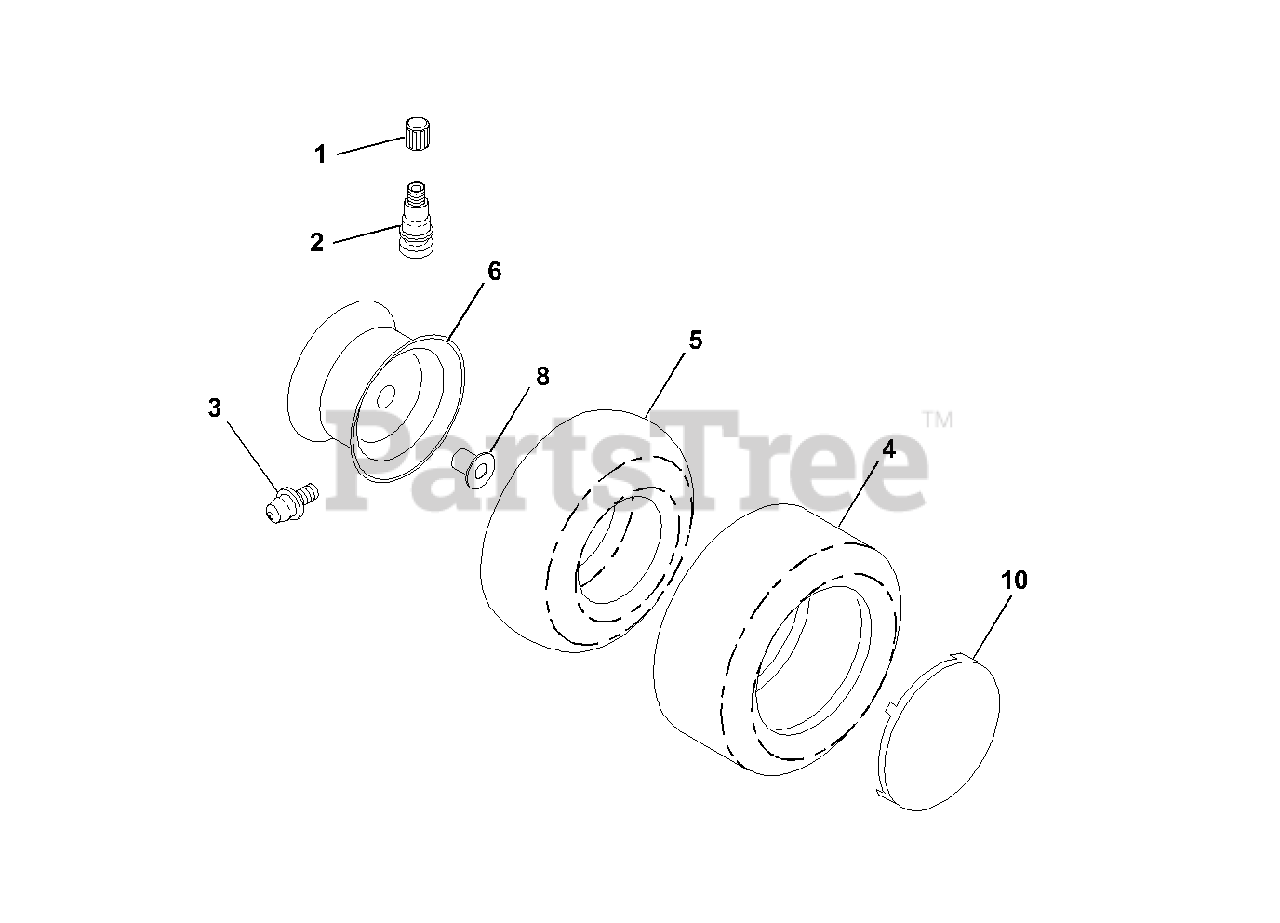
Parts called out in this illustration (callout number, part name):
1	Cap Valve Tire
2	Stem Valve
3	Fitting Grease
4	Tire F Ts 15 X 6 0 - 6 Service
4	Tire R Ts 20 X 10 - 8 Service
5	Tube Front
5	Tube Rear
6	Rim Asm 8" rear White Service
6	Rim Asm 6" front White Service
8	Bearing Flange
10	Cover Wheel 6" white
10	Cover Wheel 8" white
